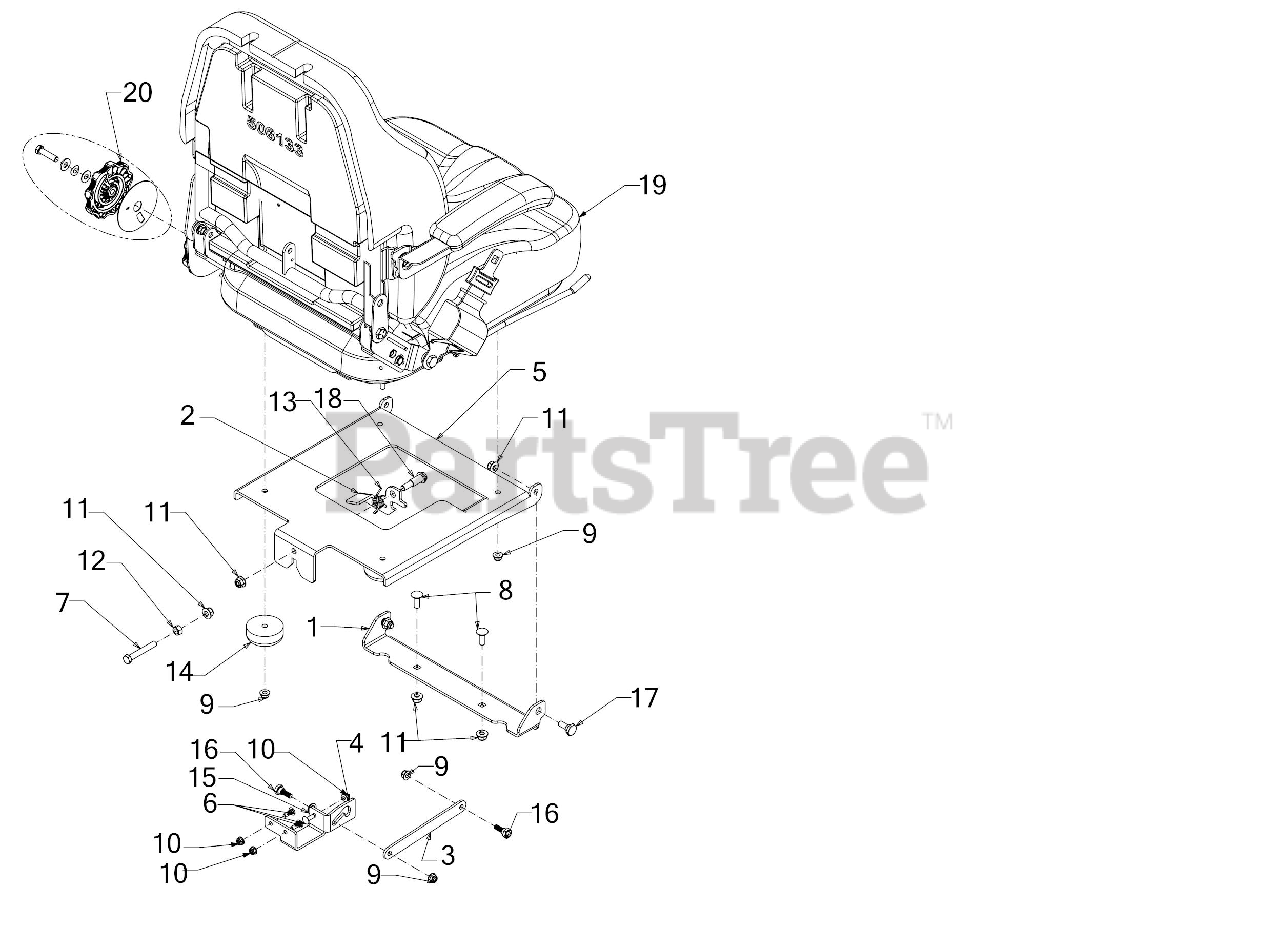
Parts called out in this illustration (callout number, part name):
1	SEAT PIVOT BRACKET
2	SEAT LATCH LEVER
3	SEAT LOCKOUT BRACKET
4	SEAT LOCKOUT MOUNT
5	SEAT MOUNTING BRACKET
6	SCREW 1/4-20 x .75 GR5
7	HEX SCREW-3/8-16X2.5 GR5
8	CARRIAGE BOLT 3/8-16 x 1.00 GR5
9	FLANGE LOCK NUT 5/16-18
10	FLANGE LOCK NUT
12	HEX NUT
13	TORSION SPRING
14	RUBBER BUMPER
15	FLAT WASHER .469X.750X.054
16	SHOULDER SCREW .437
17	SHOULDER SCREW
18	SHOULDER SCREW .50X.925
19	SEAT ASSEMBLY W/SUSPENSION
20	SEAT KNOB KIT
